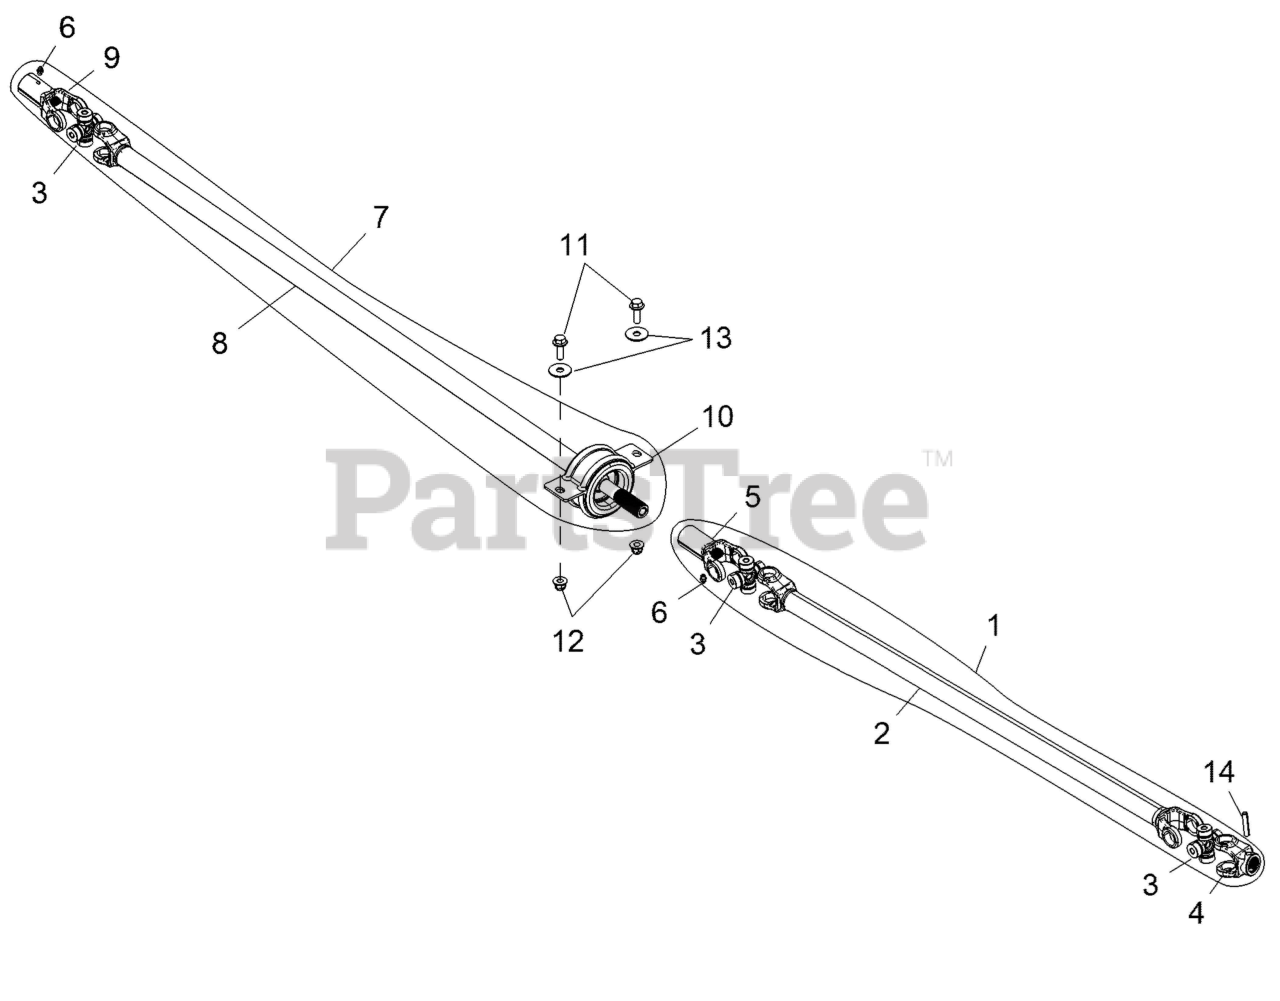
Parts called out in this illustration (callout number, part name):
1	ASM-PROPSHAFT,FRONT
2	WELD-PROPSHAFT,FRONT
3	U-JOINT-1000 SERIES
4	YOKE-PIN
5	YOKE, SLIP, INDEXED
6	FITTING, LUBRICATION
7	ASM-PROPSHAFT,REAR
8	WELD-PROPSHAFT,REAR
9	YOKE-SLIP
10	ASM-BEARING,FLEX
11	SCR-HXFL-M10X1.25X30 8.8 ZOD
12	NUT-M10X1.25,FLG,NYLOC-OLIVE D
13	WASHER, FLAT
14	PIN,SPRING(10)
